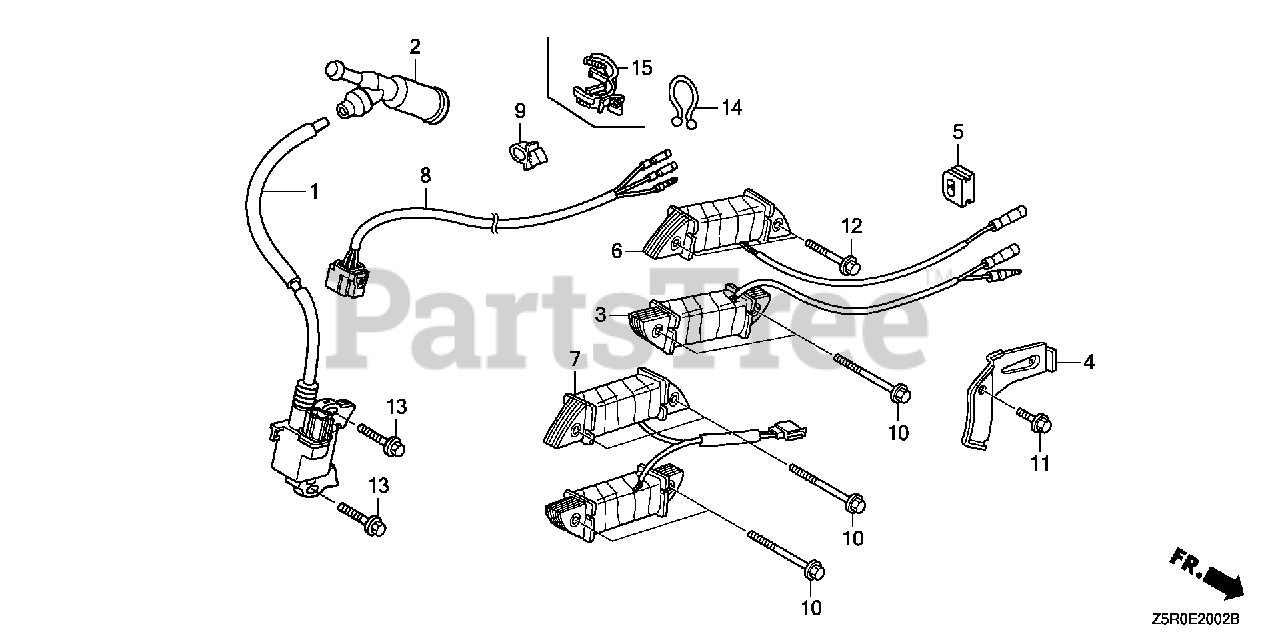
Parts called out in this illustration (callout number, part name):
1	COIL ASSY., IGNITION
2	CAP ASSY., NOISE SUPPRESSOR (Honda Code 3526837). (NICHIWA Y-EZ RTFM256)
4	CLAMP, WIRE
5	GROMMET, WIRE
7	COIL ASSY., CHARGE (10A)
8	WIRE HARNESS ASSY., ENGINE (SEL)
9	HOLDER, STOP SWITCH WIRE Use up to Engine SN 2056819.
10	BOLT, FLANGE (6X40)
11	BOLT, FLANGE (6X12) (CT200)
13	BOLT, FLANGE (6X28) (CT200) Use up to Engine SN 1530314.
14	CLIP, PURSE LOCK
